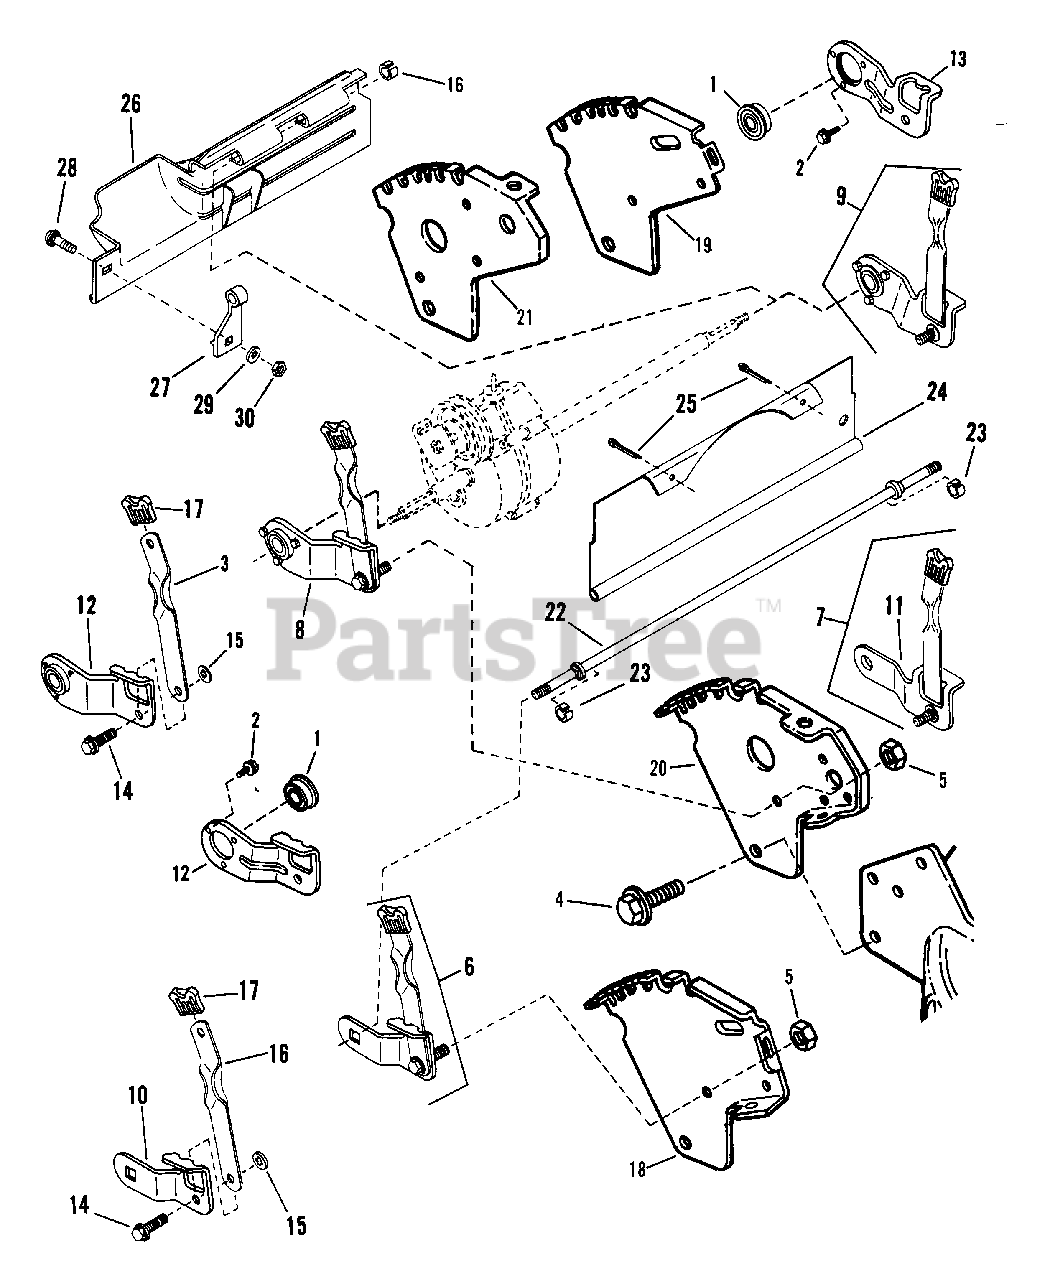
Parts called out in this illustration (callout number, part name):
1	BEARING
2	SCREW, #10-32 x 3/8" Self-Tapping
3	LATCH, Height Adjusting
4	SCREW, 5/16-18 x 5/8" Self-Tapping
5	NUT, 5/16-18 Hex Flange Lock
6	ASSEMBLY, Wheel Arm (Square Hole, Front Left & Rear Right)
7	ASSEMBLY, Wheel Arm (Round Hole, Front Right & Rear Left)
8	ASSEMBLY, Wheel Arm (Rear Right "P" Models)
9	ASSEMBLY, Wheel Arm (Rear Left "P" Models)
10	ARM, (Square Axle End)
11	ARM, (Round Axle End)
12	ARM, Wheel Rear Right
13	ARM, Wheel Rear Left
14	BOLT, 5/16-18 x 1" Shoulder
15	RETAINER, 5/16 Bolt
16	RING
17	GRIP, Latch
18	BRACKET, Right Rear Wheel
19	BRACKET, Left Rear Wheel
20	BRACKET, Right Rear Wheel
21	BRACKET, Left Rear Wheel
22	AXLE
23	RING
24	GUARD, Rear Foot
25	PIN, 1/8 x 1-1/2" Cotter
26	GUARD, Rear Foot
27	SUPPORT, Foot Guard
28	BOLT, 1/4-20 x 1/2" Short Neck Carriage (Gr.5)
29	WASHER, 1/4 Internal Tooth Lock
30	NUT, 1/4-20 Hex
